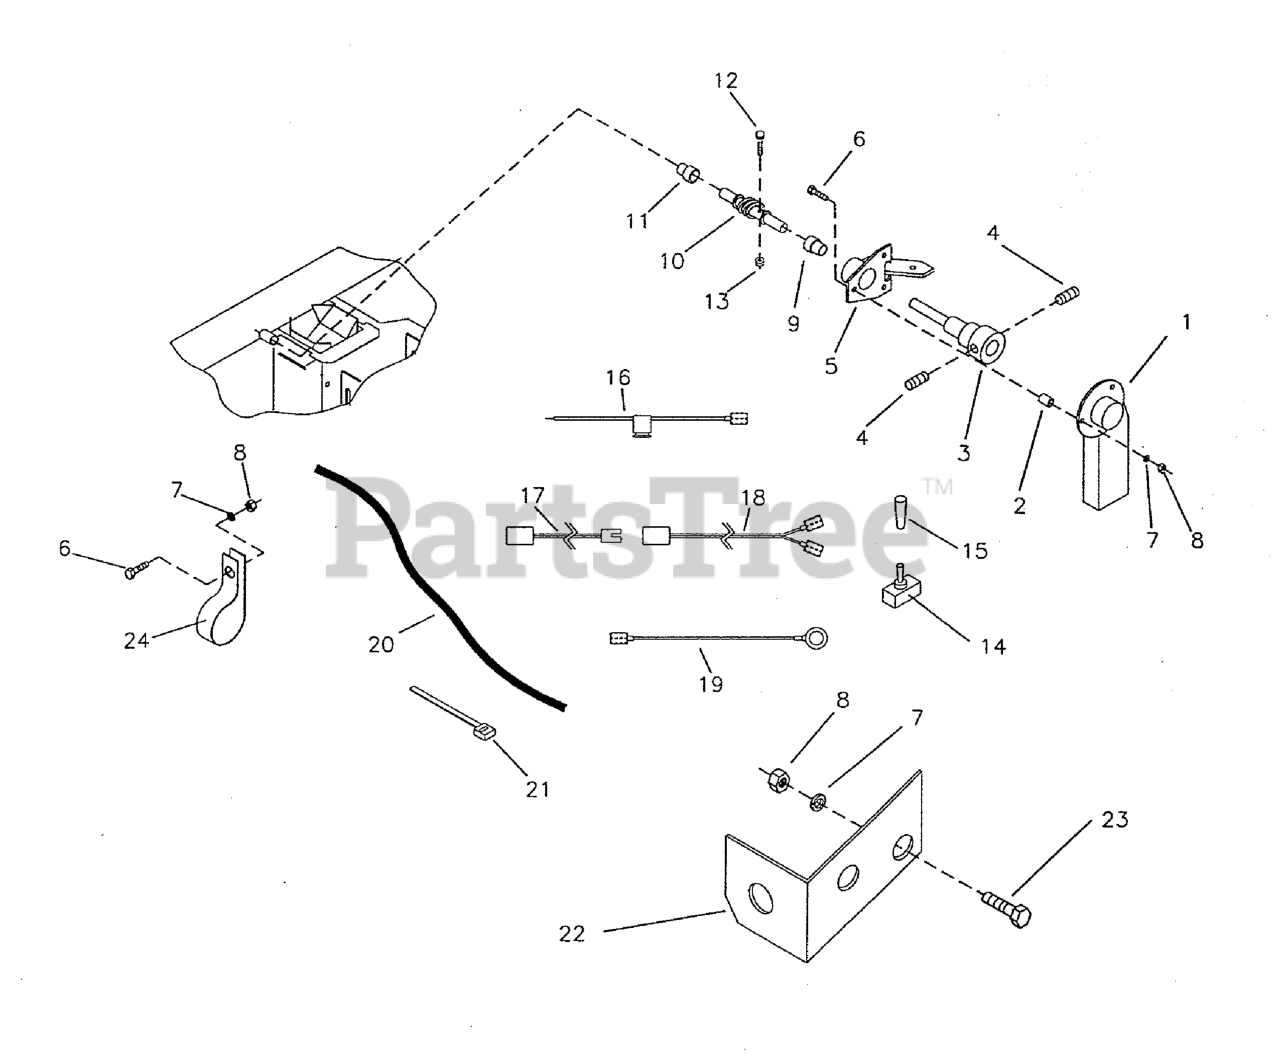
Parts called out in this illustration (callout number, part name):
1	Electric Motor
3	electric Rotation Shaft
5	Electric Rotation Support
8	Hex Nut 1/4" NC
9	Plastic Bushing 1-5/16" Lg
10	Rotation Worm
11	Plastic Bushing 1-11/16" Lg.
13	Nylon Locknut 10-24 NC
15	Rubber Cap for Switch
16	Wire with Fuse 20 Amp.
17	Double Wire 103"
18	Double Wire 7"
19	Wire # 16 Ga. X 18" Lg.
20	Plastic Wire Cover
22	Electric Support
24	Wiring Clamp
